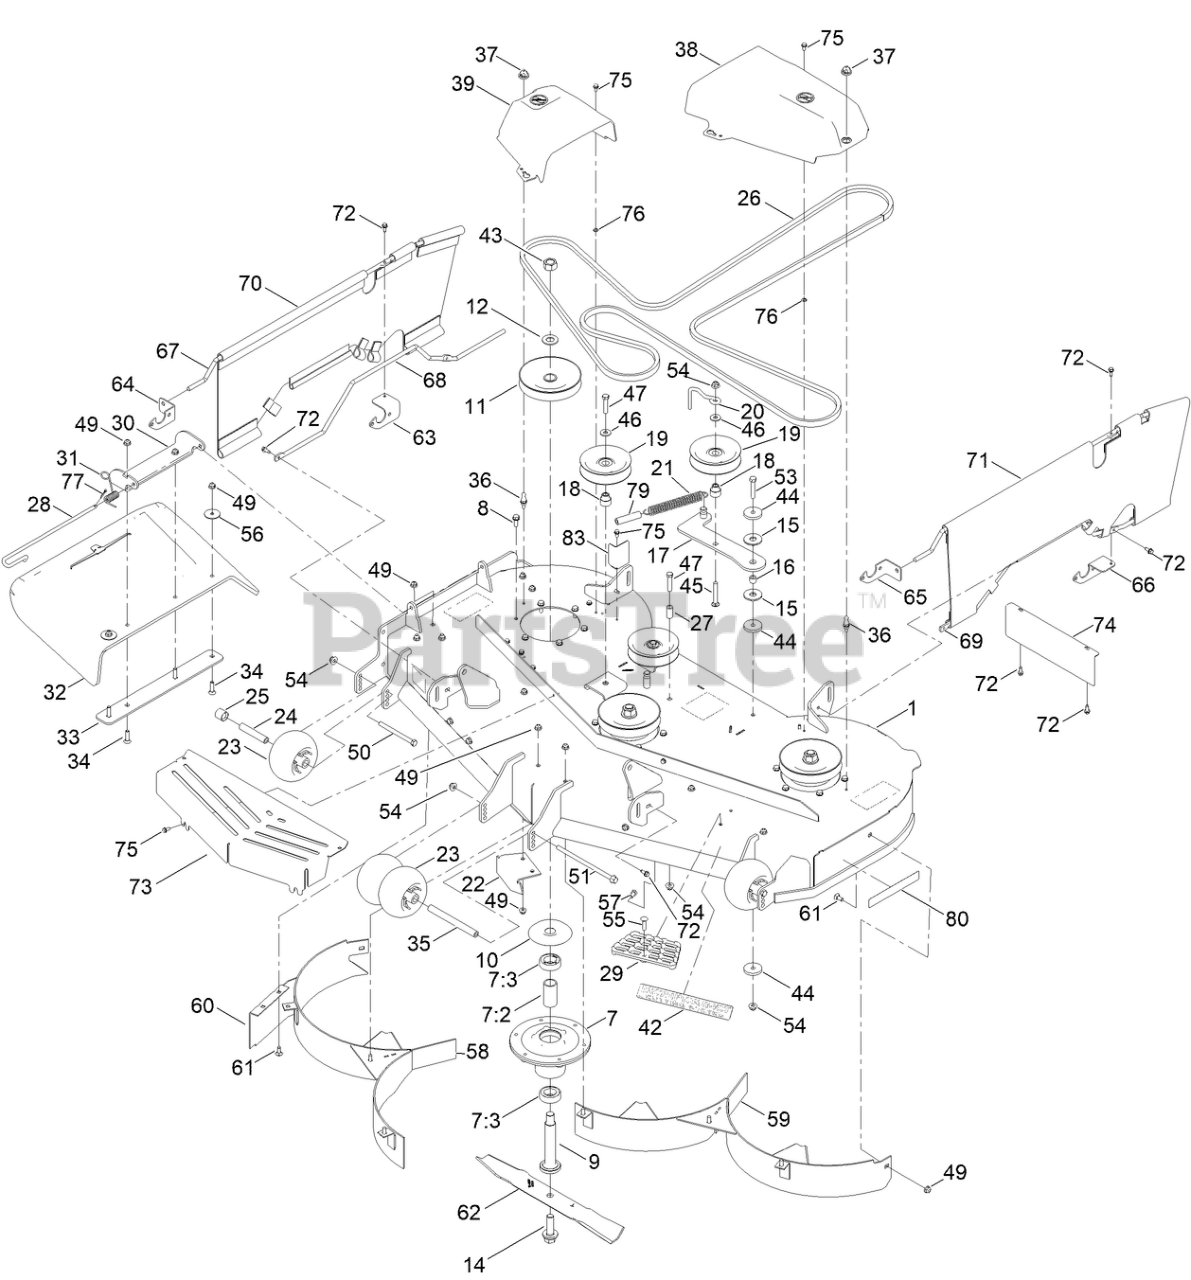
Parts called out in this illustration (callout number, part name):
1	54 IN DECK DECAL ASM
7	SPINDLE ASM
7:2	BEARING-BALL
7:3	SPACER-BEARING
8	SCREW-TAPTITE
9	SHAFT-SPINDLE
10	SHIELD-BEARING
11	PULLEY
12	WASHER
14	SCREW-BLADE
15	WASHER-FRICTION, COMPOSITE
16	SPACER
17	IDLER ARM ASM
18	BUSHING-IDLER
19	PULLEY-IDLER, FLAT
20	GUIDE-BELT, IDLER
21	SPRING-EXTENSION
22	BAFFLE-CUTOFF
23	ROLLER-SCALP, ANTI
24	TUBE-SPANNER
25	SPACER-AXLE, REAR
26	V-BELT (B SEC 174.25 EL)
27	SPACER-FENDER
28	PIN-CHUTE
29	STEP-DECK
30	BRACKET-DEFLECTOR, UPPER
31	SPRING-TORSION
32	DEFLECTOR - MOLDED
33	PLATE-DEFLECTOR
34	BOLT-CARRIAGE
35	SPACER-WHEEL
36	STUD-BALL
37	GROMMET-BALL
38	COVER-BELT, LH
39	COVER-BELT, RH
42	DECAL - IRON FORGED
43	NUT-HEX
44	WASHER-PLAIN
45	SCREW-CARR
46	WASHER-HARDENED
47	SCREW-HH
49	NUT-HF
50	SCREW-HH
51	SCREW-HF
53	HHCS 3/8-16 X 2, GR5, CZ
54	NUT-HF, NI
55	BOLT-CARRIAGE
56	WASHER-FLAT
57	SCREW-HH
58	BAFFLE-RECYCLER
59	BAFFLE-RECYCLER, LH
60	GUARD-BAFFLE
61	BOLT-CARR
62	BLADE-MULCH, 18.75 INCH
63	BRACKET-FRENCH GUARD
64	BRACKET-FRENCH GUARD
65	BRACKET-FRENCH GUARD
66	BRACKET-FRENCH GUARD
67	ROD-FRENCH GUARD
68	ROD-FRENCH GUARD
69	ROD-FRENCH GUARD
70	GUARD ASM-SIDE, POLY KNIT
71	GUARD ASM-SIDE, POLY KNIT
72	SCREW-HWH
73	BRKT-SHIELD, FRONT
74	PLATE-GUARD REAR
75	SCREW-HWH
76	NUT-RETAINING
77	PIN-COTTER
79	HOSE-BREATHER
80	DECAL-RECYCLER
83	BRACKET-GUARD, CE
